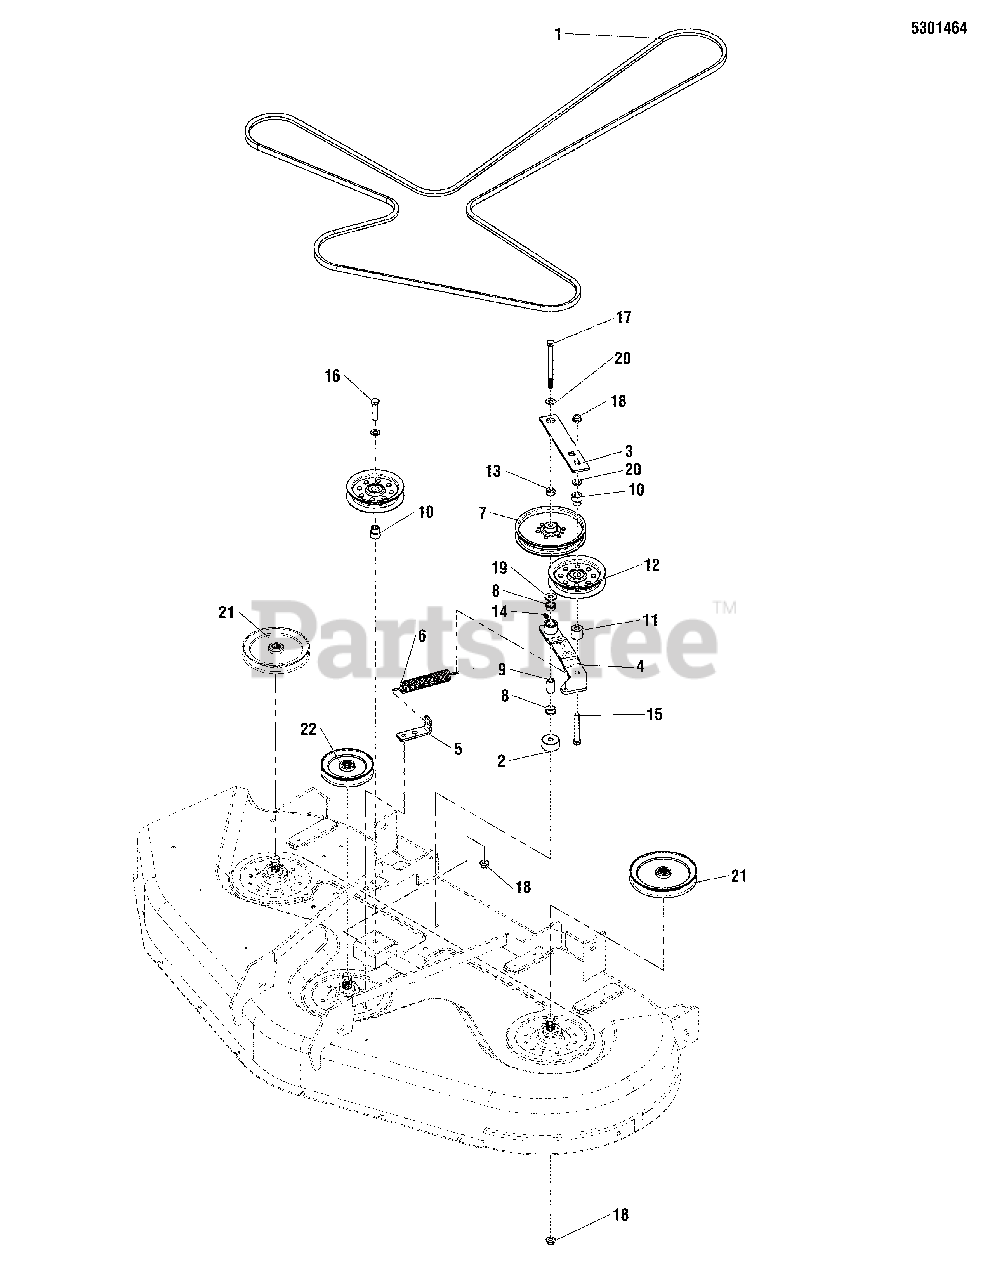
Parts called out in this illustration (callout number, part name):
1	BELT KIT, A SECTION, 163.00 EL (5101405)
2	SPACER, .39 X 1.50 X .75 - YZ
3	MOUNT, IDLER TENSION - 54 - RED
4	WELD, DECK IDLER ARM, CON/SNP Z - RED
5	BRACKET, SPRING ANCHOR - SNP/CON Z - RED
6	SPRING, EXTENSION, 1.00
7	PULLEY, FLAT IDLER, 5" W/KOYO
8	BUSHING, 0.628IDX0.751ODX0.400LG PWDR MTL
9	SPACER, 0.39 IDX0.625ODX1.15 LG CASE HARD
10	SPACER, HYDRO PULLEY
11	SPACER, .39 X 1.00 X .88
12	PULLEY, IDLER
13	SPACER, .39 X .75 X .38
14	GREASE FITTING, 1/4-28 STRAIGHT
15	BOLT, 3/8-16 X 2-3/4" GD5 CZ
16	BOLT, 3/8-16 X 1-3/4" GD5 CZ
17	BOLT, 3/8-16 X 4-1/2" GD5 CZ
18	NUT, 3/8-16 HEX NYLOCK FLANGE
19	WASHER, 3/8" USS
20	WASHER, 3/8 SAE
21	WELD, PULLEY, DECK DRIVE -4.477OB -PLAIN
22	WELD, PULLEY, DECK DRIVE -5.70 OB -PLAIN
